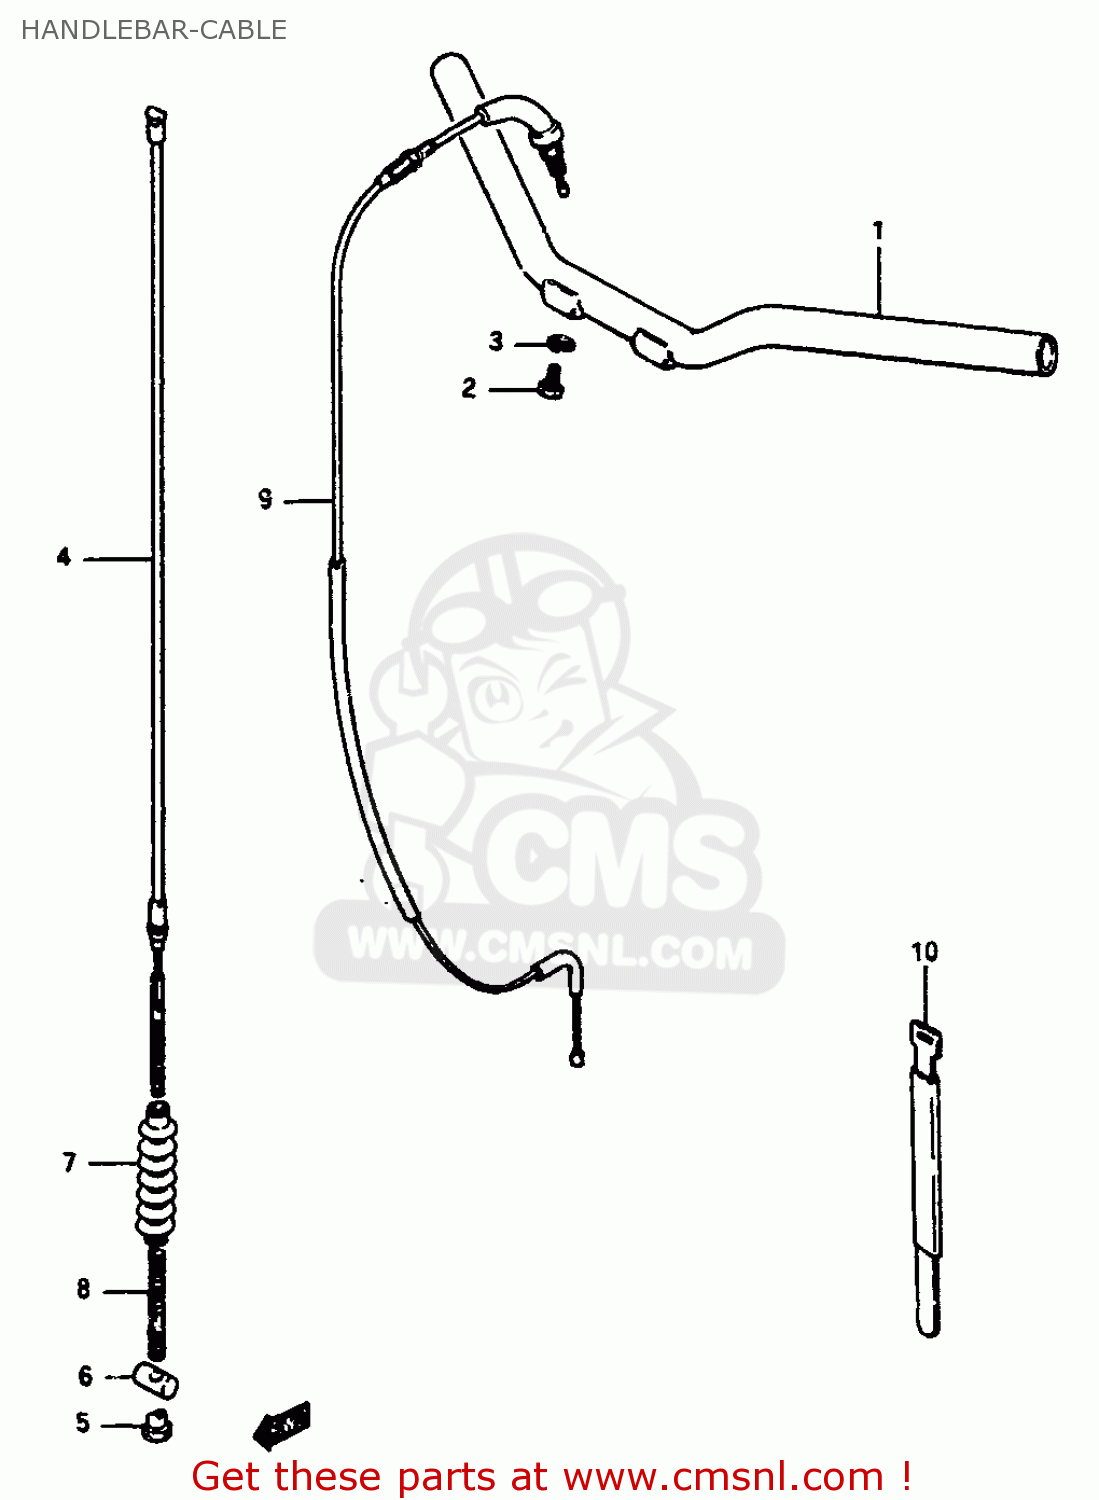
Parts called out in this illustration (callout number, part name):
1	HANDLEBAR
2	BOLT,8X16
3	LOCK WASHER
4	CABLE ASSEMBLY,FRONT BRAKE
5	NUT
6	PIN,10X19
7	SEAL,DUST(7X16X75)
8	SPRING
9	CABLE ASSEMBLY,THROTTLE
10	CLAMP
